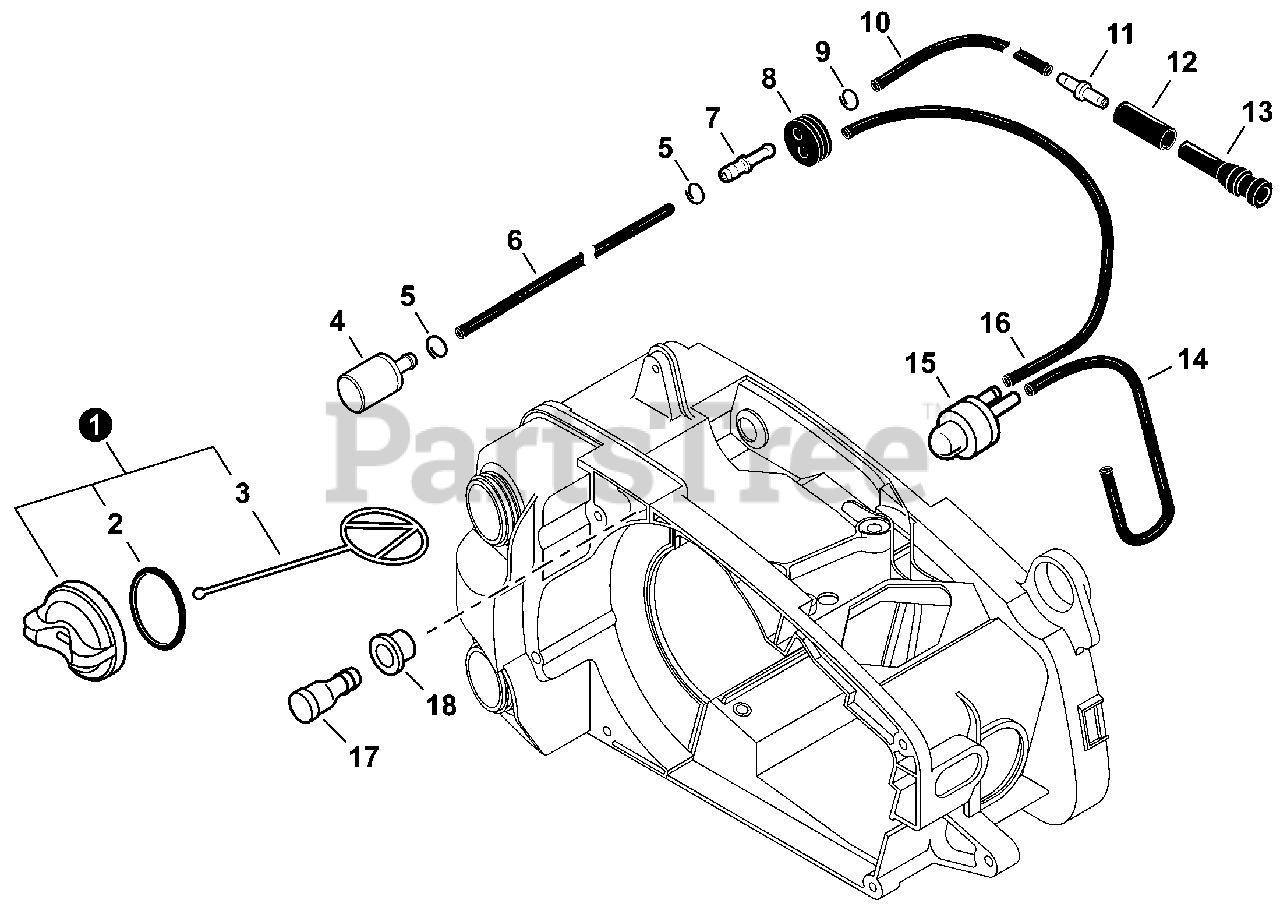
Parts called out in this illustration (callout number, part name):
1	CAP ASSY, FUEL - ORANGE
3	CONNECTOR, CAP L= 60 MM
4	FILTER, FUEL
5	CLIP Ø6
6	PIPE, FUEL 3×5×95
7	CONNECTOR, PIPE Ø5ר3.5
8	GROMMET, FUEL
10	PIPE, FUEL 3×5×165
11	CONNECTOR, PIPE
12	TUBE Ø6.5×8.5×18
13	PIPE, FUEL 10×6×32
14	PIPE, FUEL 2.4×5×75
15	BULB, PURGE
16	PIPE, FUEL 2.4×5×295
17	VENT ASSY
18	GROMMET, FUEL
